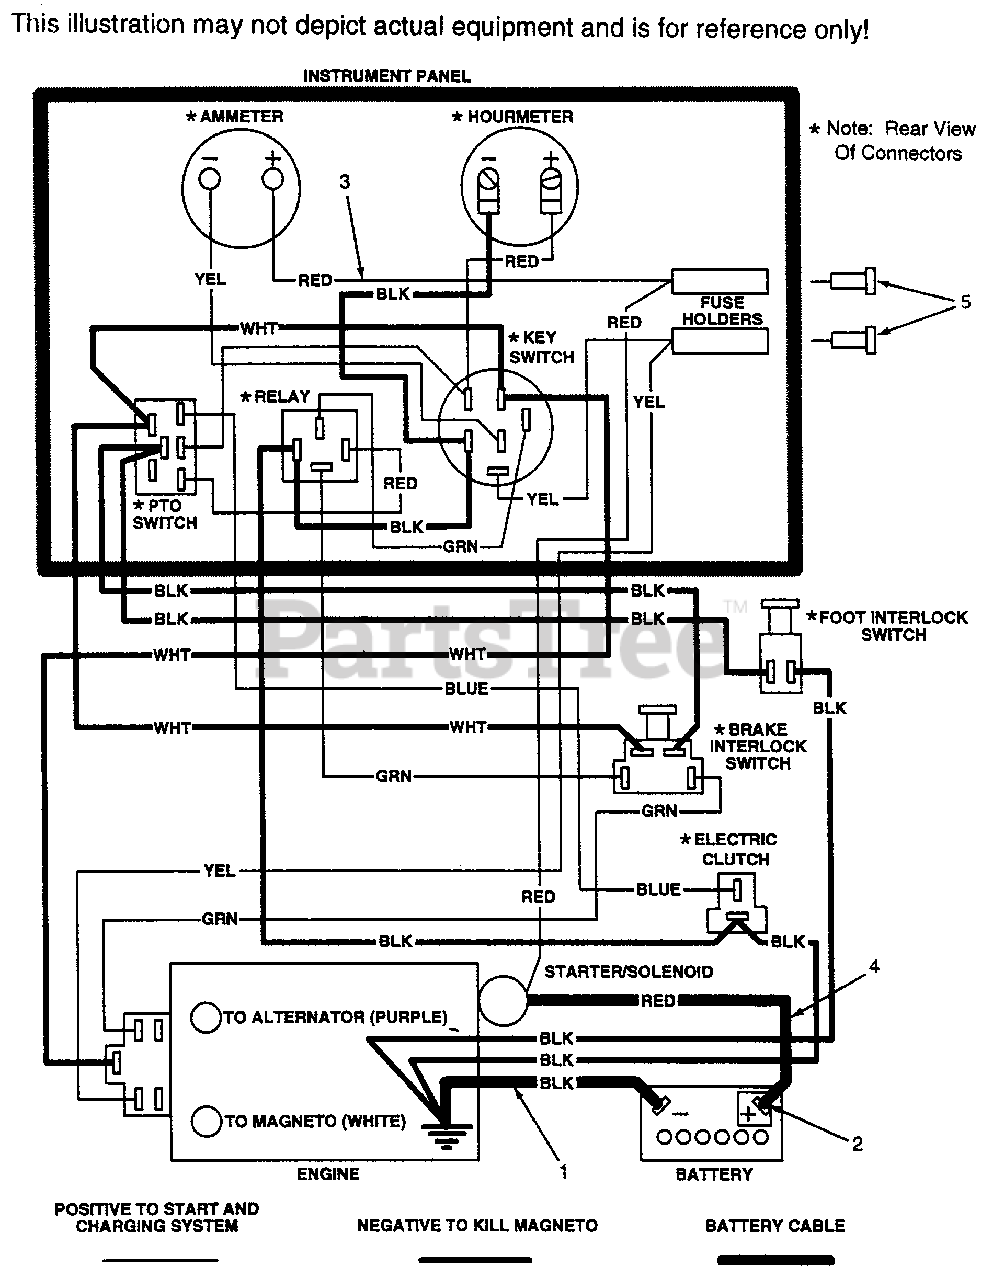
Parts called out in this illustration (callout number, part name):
1	BATTERY CABLE, 36" BLACK
2	RUBBER BOOT
3	WIRE HARNESS, STHM
4	BATTERY CABLE, 25" RED
5	FUSE, 20 AMP BLDEE AUTOMOTIVE
